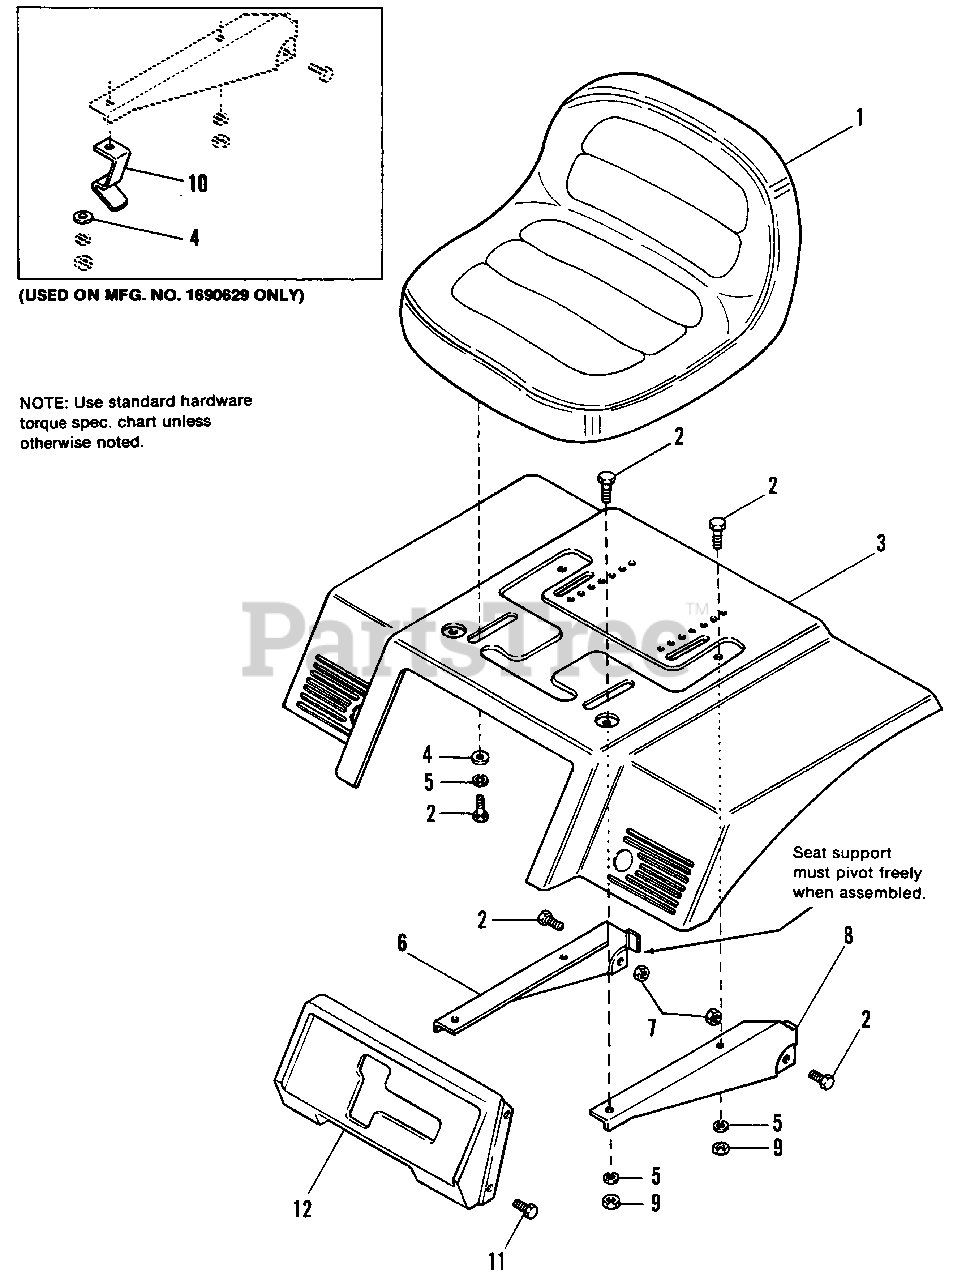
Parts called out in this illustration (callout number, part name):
2	CAPSCREW, Hex Hd., 5/16-18 x 3/4
3	DECK, Seat
4	WASHER, Plain, 5/16 (Qty. 4 used on 1690684)
5	LOCKWASHER, 5/16
6	SUPPORT, Seat, R.H.
7	LOCKNUT, Hex, 5/16-18
8	SUPPORT, Seat, L.H.
9	NUT, Hex, Full, 5/16-18
10	LATCH, Spring (Used on 1690629 only)
11	SCREW, Hex, Taptite, 1/4-20 x 1/2
12	PANEL, Shift
